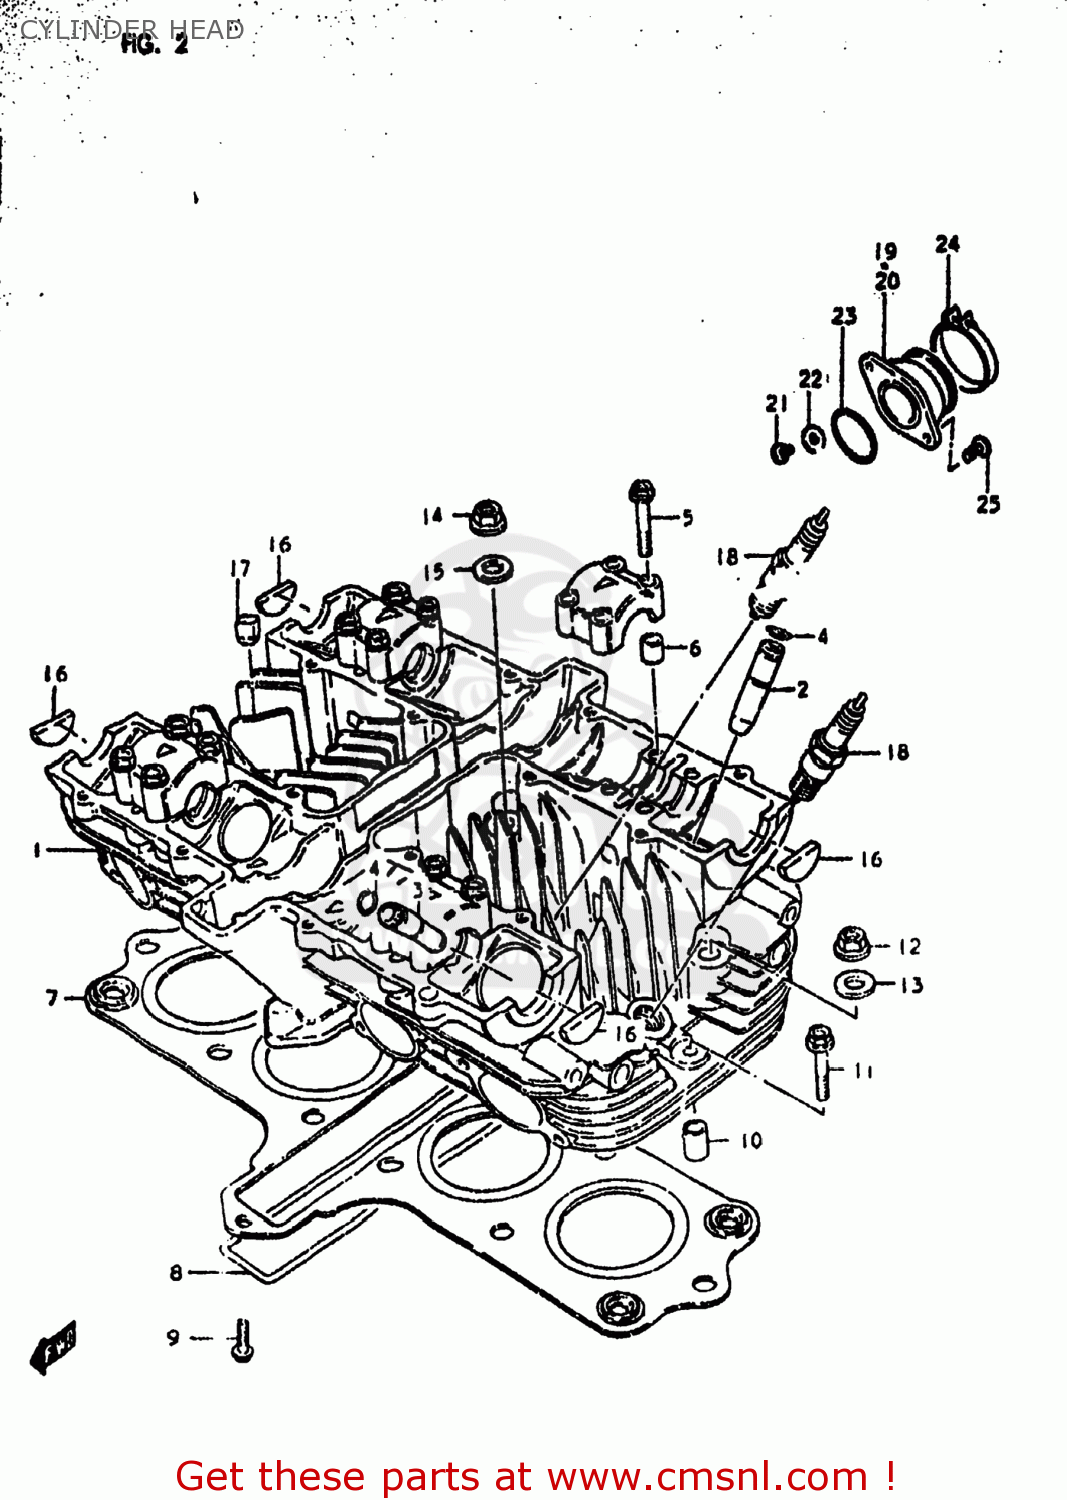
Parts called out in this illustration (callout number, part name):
1	HEAD ASSEMBLY,CYLINDER
2	GUIDE,VALVE
3	GUIDE,VALVE
4	RING,SNAP
5	BOLT(6X39)
6	PIN(6.2X8X11)
7	GASKET,CYLINDER HEAD (MCA)
8	O RING(D:3,ID:26X157)
9	BOLT
10	PIN
11	BOLT,UNDER
12	NUT
13	GASKET (NAS)
14	NUT
15	WASHER(8.5X19X2.3)
16	PLUG
17	PAD
18	SPARK PLUG
19	PIPE,INTAKE,R
20	PIPE,INTAKE,L
21	BOLT
22	WASHER
23	O-RING
24	CLAMP
25	SCREW
